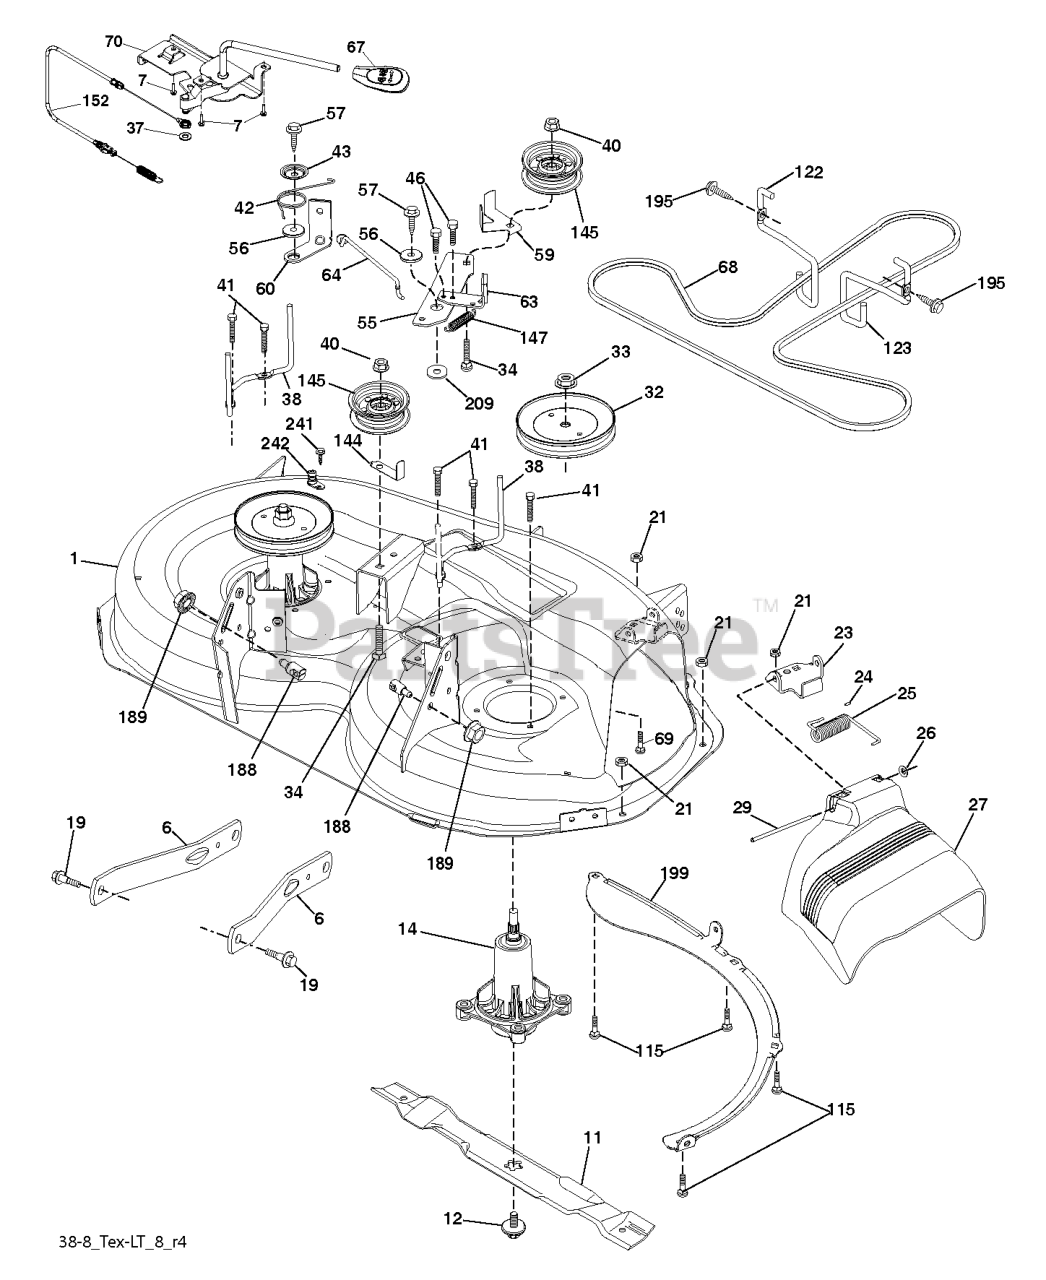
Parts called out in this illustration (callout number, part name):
6	ARM.SUSPENSION.MOWER.R
11	BLADE.2 IN 1.38"DECK.BLACK
12	SCREW.SEMS.7/16-20X1.HEX.HEAD
14	KIT.MANDREL.NONGREASE.TALL
19	BOLT.SHOULDER
23	BRKT.DEFLECTOR.38"2005+
24	CAP-SLEEVE LT
25	SPRING.TORSION.DEFLECT
26	NUT PUSH M
27	SHIELD, DEFLECTOR
32	PULLEY.MANDREL.5.0.PD.38"
34	GSPW Bolts
37	WASHER PLAIN WASHER 3/8 X 0.08
38	KEEPER BELT LH MANDREL
40	NUT LOCK FLG 3/8-16 UNC
41	BOLT.HEX.WASHR.HED.313-18X1.19
42	SPRING.TORSION.BRAKE
43	SRPING.TORSION.RETAINE
46	SCREW.1/4-20X5/8
56	SPACER.RETAINER
57	SCREW 3/8-16X1
59	GUARD, BELT
60	ARM BRAKE MOWER RH 38"
63	RP ARM.BRAKE.MOWER.38"LH.TEX
64	LINK BRAKE
67	HANDLE.CLUTCH.CABLE.LT
70	CLUTCH.ASM.MANUAL.LT.PRED
115	BOLT.CARR.5/16-18X5/8.SHORT
122	KEEPER BELT ENGINE LH
123	KEEPER BELT RH
144	KEEPER BELT
145	PULLEY.IDLER.48"PRIMARY
147	SPRING RETURN
152	CABLE.CLUTCH.MANUAL.
188	STUD.W/"D"ANTI-ROTATION
195	SCREW, 3/8-16X3/4
199	BAFFLE.VORTEX.FRONT.38"
241	SCREW.TT.#10-32X.5.3/8.FLANGE
242	PORT.WASHOUT
